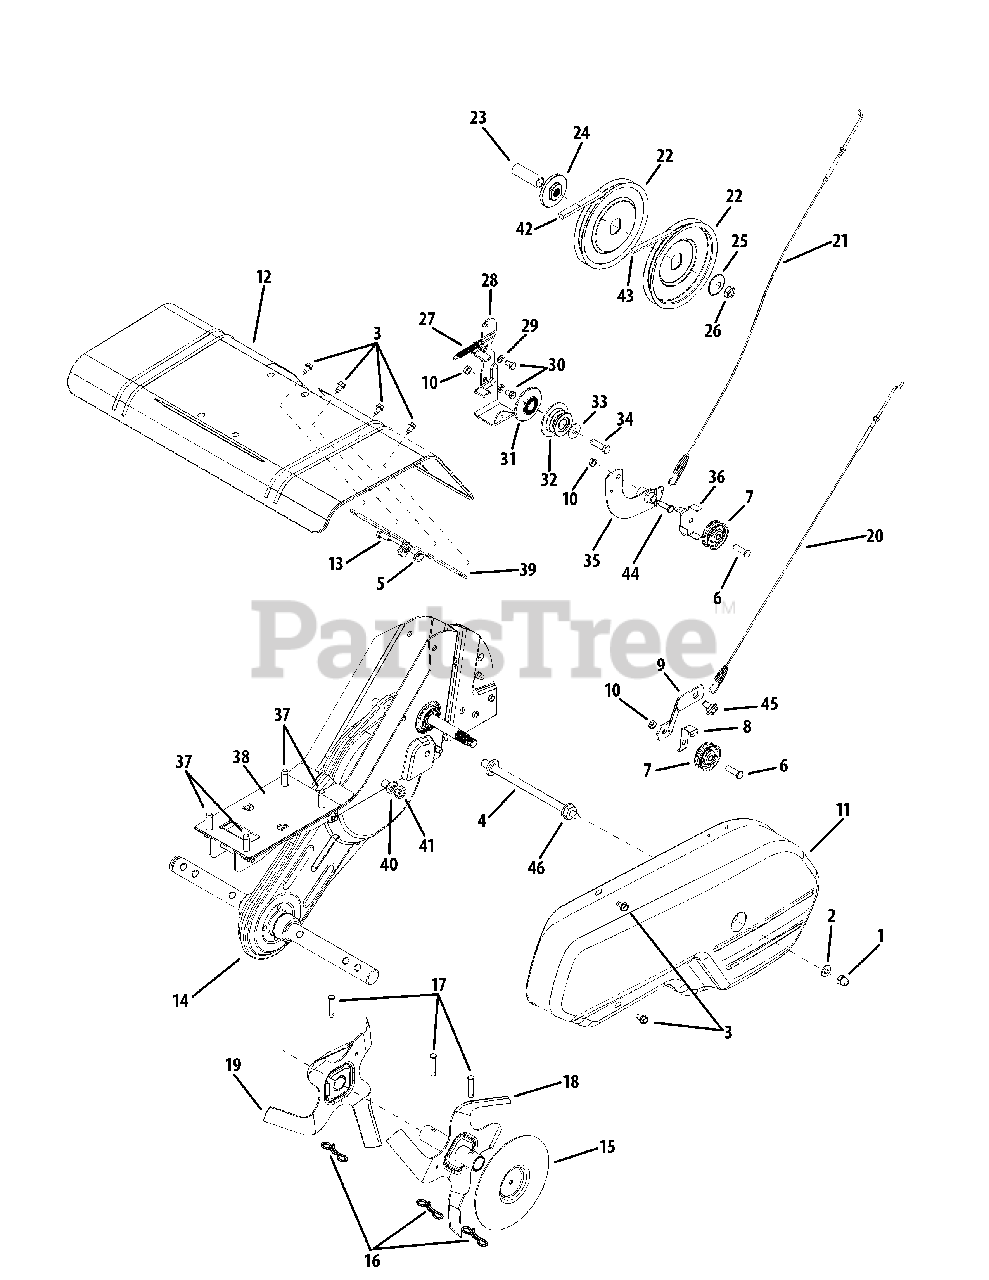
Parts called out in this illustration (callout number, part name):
1	Hex Lock Stop Nut 1/4-28
2	Flat Washer .266 ID x .625 OD
3	Hex Wash S-Tapp Scr 1/4-20 x .50
4	Belt Cover Bolt
5	Flange Locknut 5/16-18 Gr. F, Nylon
6	Hex Screw 3/8-16 X 1.25
7	Flat Idler 2.0 X 1.0 w/flange
8	Belt Idler keeper
9	Idler Bracket
10	Hex Cent L-Nut 3/8-16
11	Belt Cover
12	Tine Shield
13	Hex Bolt 5/16-18 x .75" Lg. Gr. 5
14	Chain Case Assembly Complete
15	Tine Disc Ends
16	Bow Tie Cotter Pin
17	Clevis Pin 3/8 Dia
18	Outer Tine Ass’y LH
18	Outer Tine Ass’y RH
19	Inner Tine Ass’y - LH
19	Inner Tine Ass’y - RH
20	Forward Clutch Cable
21	Reverse Clutch Cable
22	Flat Pulley 6" Dia.
23	Spacer .64" Dia. x 2.4" Lg.
24	Pulley Mounting Adapter
25	Bell. Washer .56 ID x 1.5"
26	Hex Jam Nut 1/2-20 Gr. 5
27	Return Spring 2.7" Lg.
28	Reverse Mounting Bracket
29	L-Wash 5/16 ID
30	Hex Screw 5/16-24 X .62
31	Outer Engine Pulley Half
32	Outer Engine Pulley Half
33	Cupped Washer .396 ID x 1/14"
34	Hex Bolt 3/8-24 x 1.0
35	Reverse Arm Ass’y
36	Keeper Plate
37	Hex Washer Scr 3/8-16 x 1.25
38	Engine Plate
39	Tine Shield Support
40	Lockwasher 7/16 ID
41	Hex Jam Nut 7/16-20
42	Engine Pulley 5.56 Dia x 3.56 Dia
43	"V" Belt (Reverse)
44	Axle Bolt
45	Shoulder Bolt
46	Hex Flange L-Nut 5/16-18
